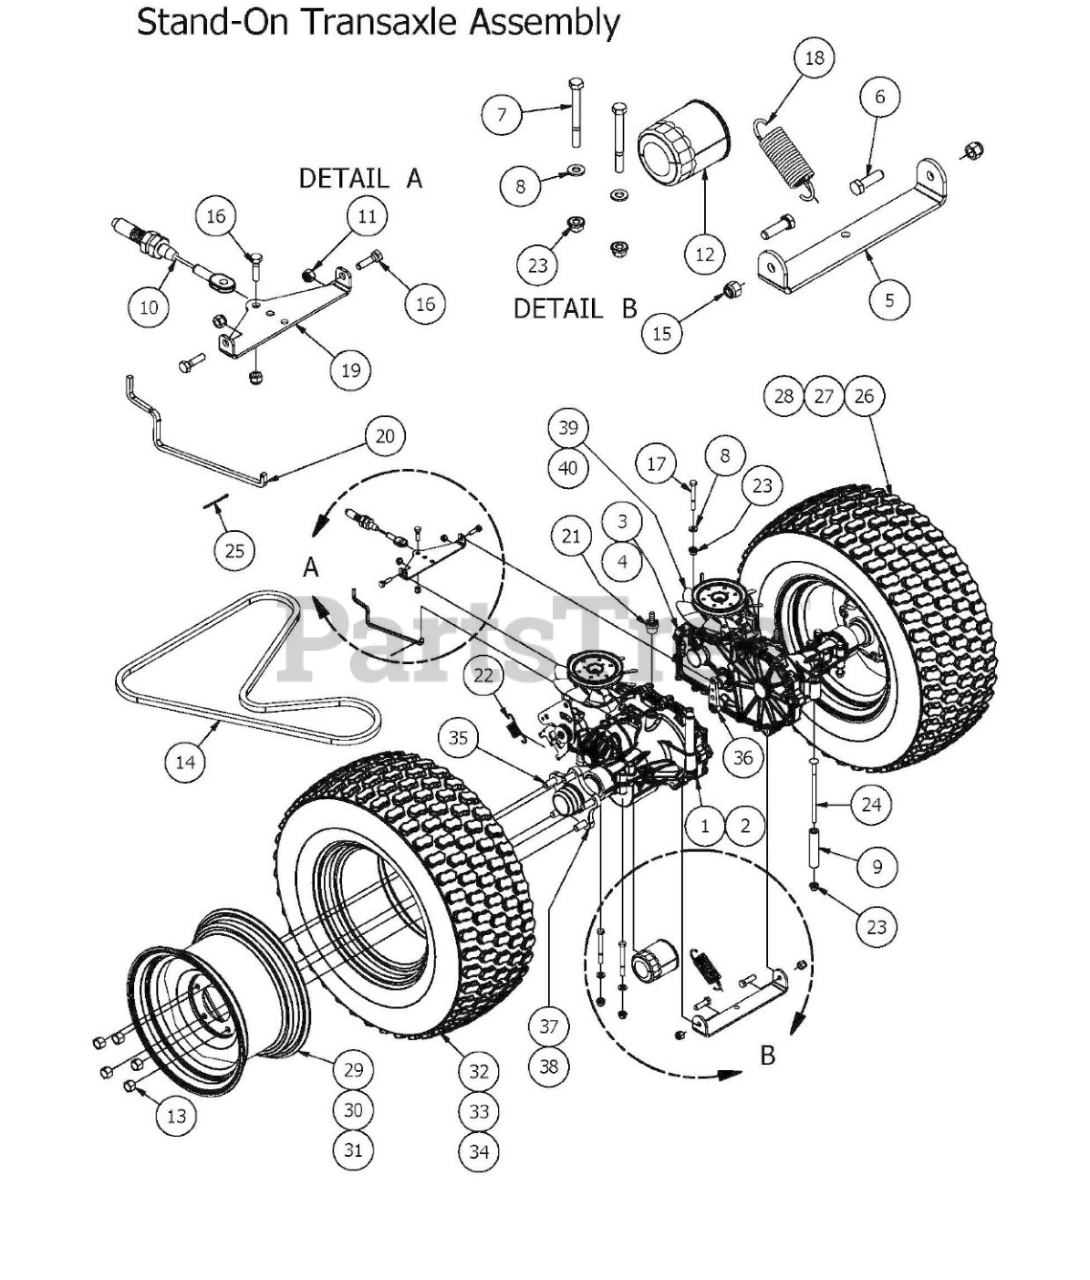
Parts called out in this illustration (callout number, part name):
1	Left 3400 Transaxle
2	Left 3100 Transaxle (36" Stand-On only)
3	Right 3400 Transaxle
4	Right 3100 Transaxle (36" Stand-On only)
5	Crossover Bar for ZT 2016
6	3/8" x2" Hex Bolt
7	5/16" x 3" Hex Bolt
8	5/16" Flat Washer
9	2017 Transaxle Spacer
10	Brake Cable
11	1/4" Nylock Nut
12	Transaxle Hydro Filter
13	Acorn Lug Nut (8 for 36" Stand-On)
15	3/8 Nylock Nut
16	1/4-20 x 1 GR 5 hex bolt zinc
17	5/16" x 2 1/2" Bolt
19	Brake Bracket
20	MZ Brake Release Bar
21	45 degree fitting
22	Spring for Stand On Models
23	5/16" Nylon Flange Nut
24	5/16" x 6" Carriage Bolt
25	Cotter Pin-Brake bar on Mz
26	23 x 10.50 -12 Tire and Wheel Assembly (54" and 61" Stand-On)
27	23 x 8.50 - 12 Tire and Wheel Assembly (48" Stand-On Only)
28	21 x 7- 10 Tire and Wheel Assembly (36" Stand-On Only)
29	12 x 10.5 Wheel (54" and 61" Stand-On)
30	12 x7 Wheel (48" Stand-On Only)
31	10" Wheel (36" Stand-On Only)
32	23 x 10.50 -12 Tire (54" and 61" Stand-On Only)
33	23 x 8.50 12 Tire (48" Stand-On Only)
34	21x7-10 Tire (36" Stand-On only)
35	Transaxle Wheel Studs (8 for 36 Stand-On)
36	Transaxle Brake Lever
37	Transaxle Hub
38	Transaxle Hub (36" Stand-On only)
39	Fan/Pully Kit
40	Fan/Pully Kit (36" Stand-On only)
